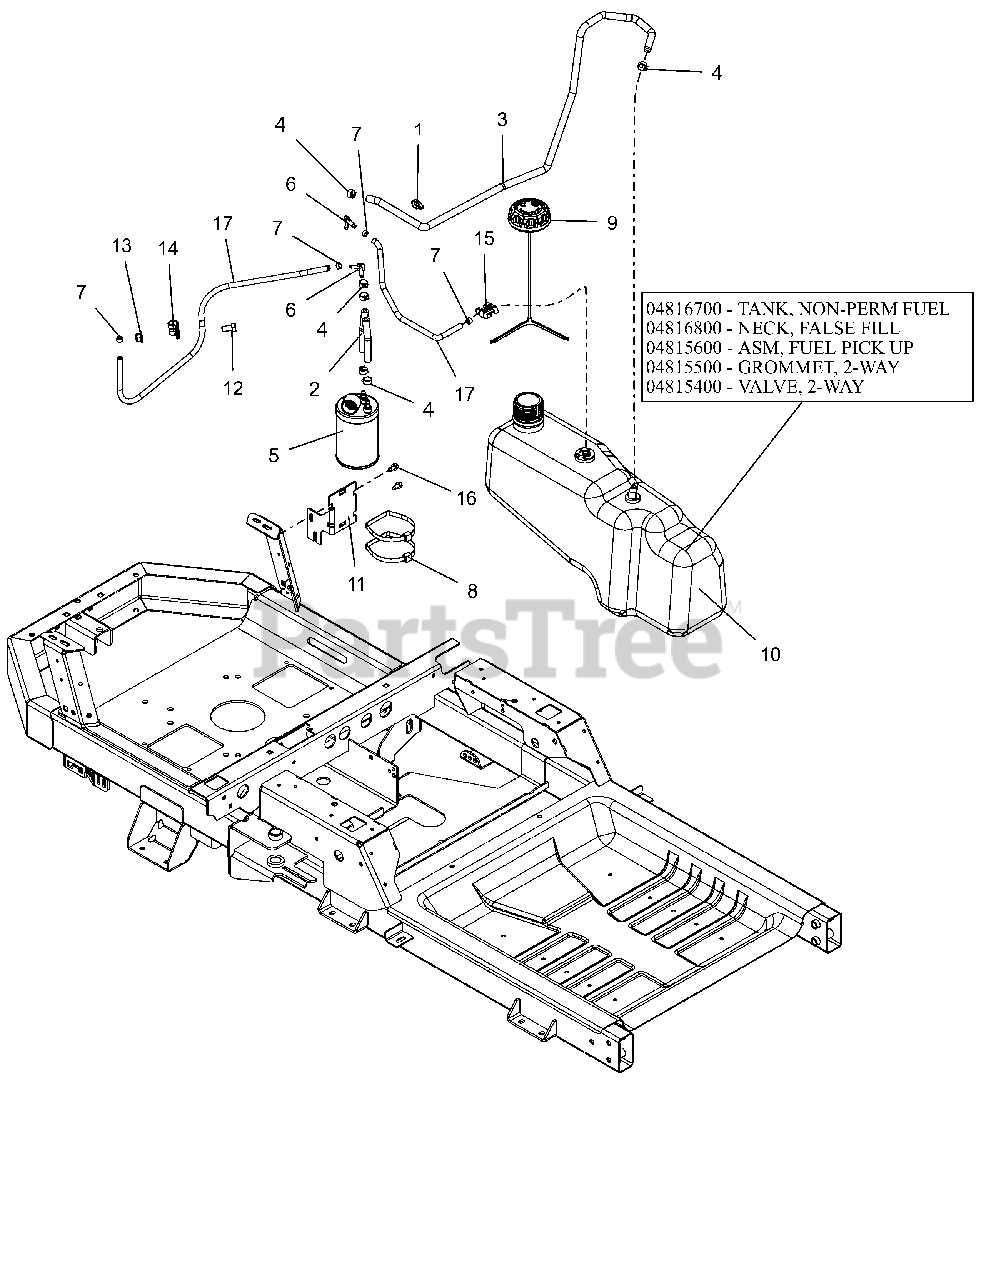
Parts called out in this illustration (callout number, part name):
1	ROUTING CLIP (1/2" ID)
2	HOSE, .25 LOW-PERM BULK GAS
3	HOSE, .25 LOW-PERM BULK GAS
4	CLAMP, FUEL LINE
5	CARBON CANISTER, 300CC
6	FITTING-3/16X1/4 90DEGREE VAC
7	CLAMP-HOSE, SPRING .188
8	P-PLASTIC TIE STRAP LARGE
9	CAP, FUEL VENT-IN 2.25" RATCH.
10	ASM,TANK NON-PERM FUEL
10	TANK, ZOOM/ZT NON-PERM, FUEL
10	NECK, FALSE FILL ZOOM/ZT
10	ASM, FUEL PICK-UP ZOOM/ZT 2015
10	GROMMET, 2-WAY
10	VALVE, 2-WAY
11	BRKT, CARB CANISTER MOUNT
12	@BLT-HEX .38-16X.75 GR5 YWZC
13	@NUT-LK-NYL-FLG .38-16 YWZC
14	CLAMP, CUSHIONED STEEL
15	CLIP, T, .38-.50
16	SCR-TAP .25-20X.50 HWH TR YWZ
17	HOSE, .188 LOW-PERM BULK GAS
